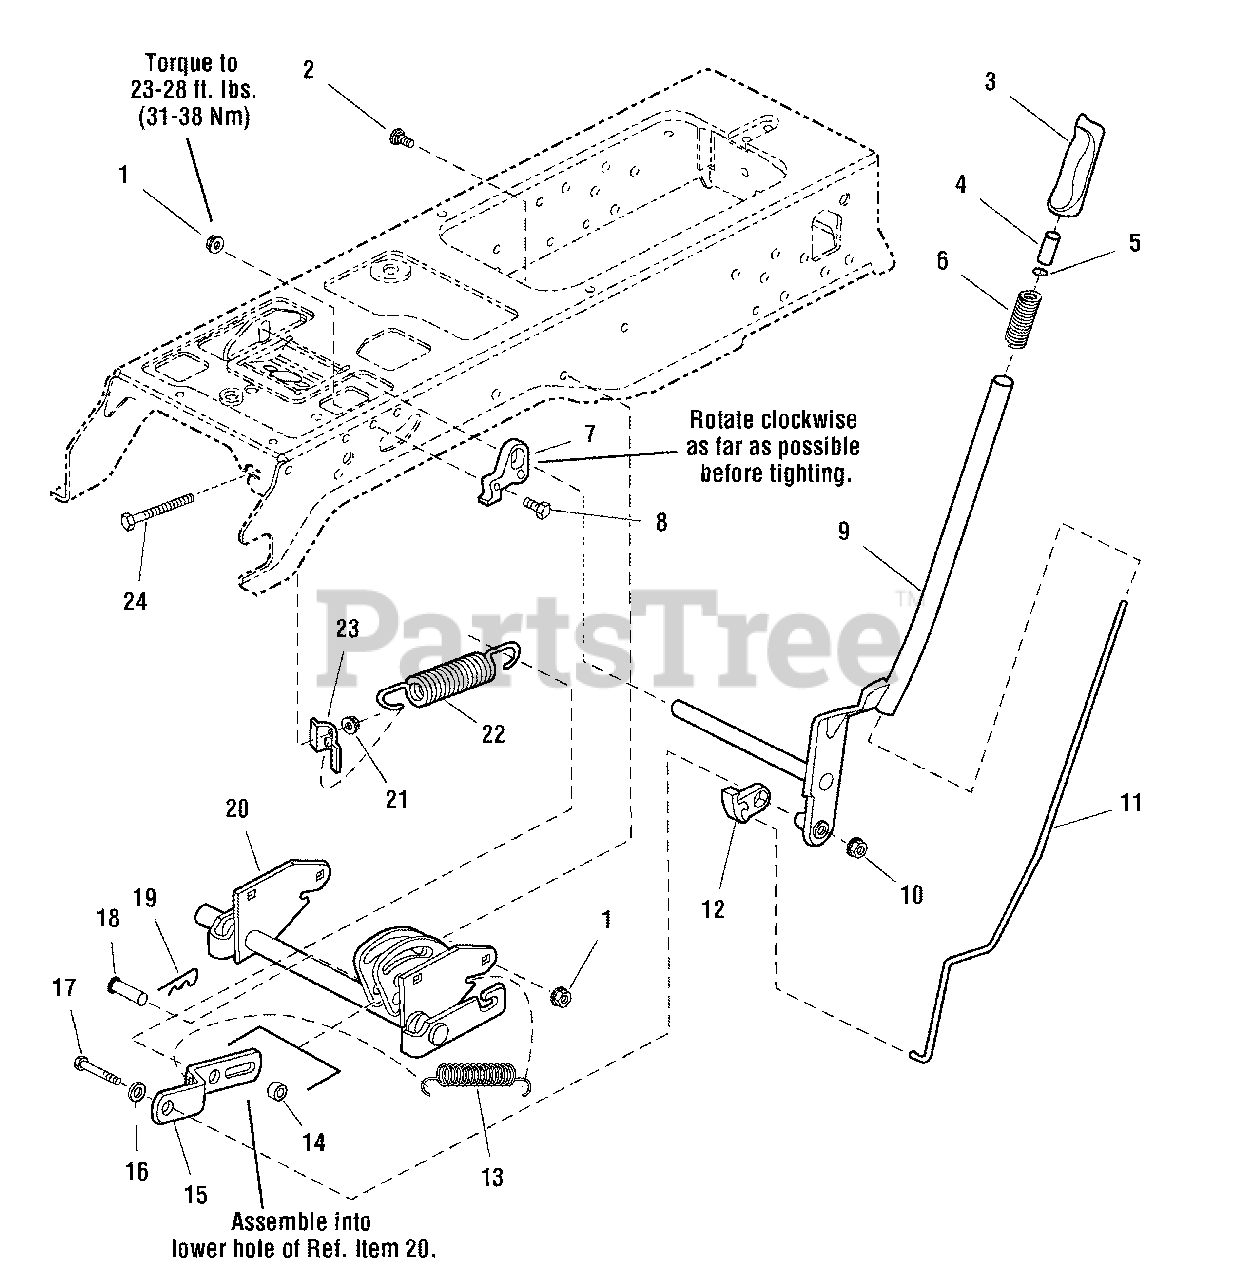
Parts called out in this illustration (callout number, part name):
1	NUT, Hex Whiz Lock Flange, 5/16-18, Large, Black
2	BOLT, Carriage, 5/16-18 x 3/4
3	GRIP, Lift Lever
4	BUTTON, Red Nylon, for 1/4 Rod
5	NUT, Push
6	SPRING, Compression, Lift Lever
7	QUADRANT, Lift, Powdered Metal
8	CAPSCREW, Hex Head, 5/16-18 x 1, G8, Black
9	LEVER ASSEMBLY, Lift
10	NUT, Hex KEPS, 5/16-18
11	ROD, Latch
12	LOCK, Lift, Powdered Metal
13	SPRING, Extension
14	SPACER, 1/2 x 3/4 x 23/32
15	BAR, Lift, 9-7/8 Long
16	WASHER, 5/16, Black
17	CAPSCREW, Hex Head, 5/16-18 x 2-1/4
18	PIN, Flat Head Drilled, 1/2 x 2-1/8 Long
19	CLIP, Hair Pin, 2-9/16 Long
20	SHAFT ASSEMBLY, Lift
21	NUT, Speed, 5/16-18, Lug
22	SPRING, Compression
23	RETAINER, Spring Flat
24	CAPSCREW, Hex Washer Head, 5/16-18 x 4-1/2
